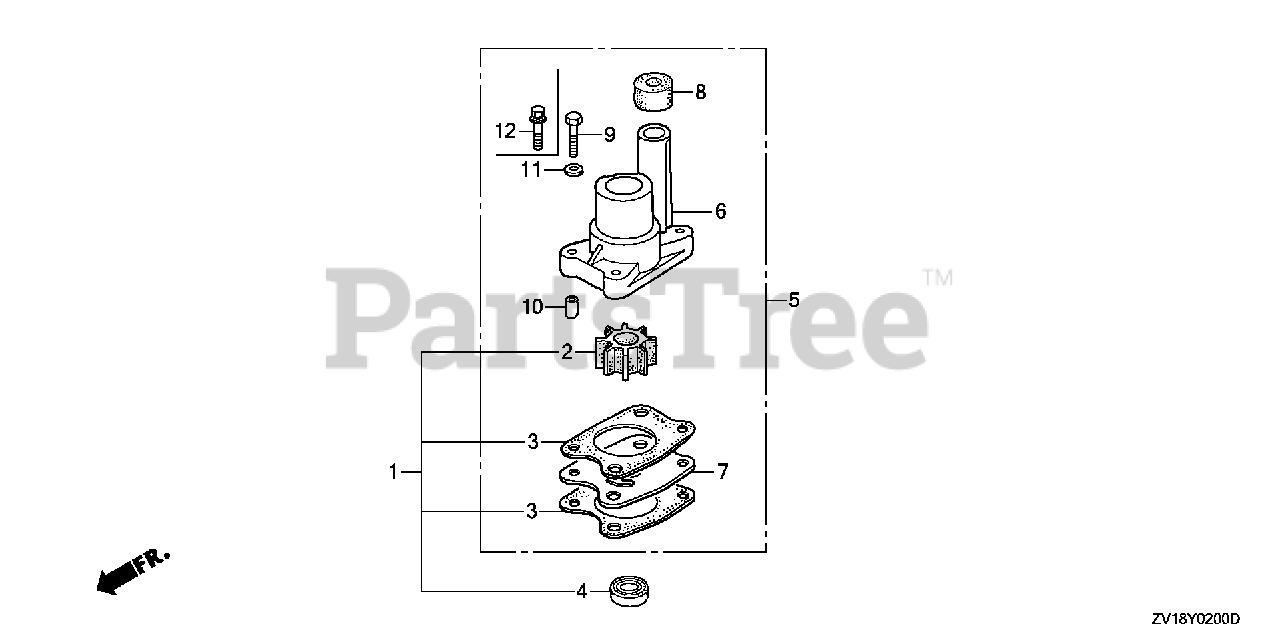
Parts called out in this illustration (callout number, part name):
1	IMPELLER KIT, WATER PUMP
2	IMPELLER, PUMP
3	GASKET, IMPELLER
4	SEAL, WATER (13MM) (ARAI)
5	PUMP KIT, IMPELLER
6	HOUSING, IMPELLER
7	COVER, IMPELLER
8	RING, WATER TUBE SEAL
9	BOLT, HEX. (6X28)
10	COLLAR B, DISTANCE
11	WASHER, PLAIN (6MM) Use from Frame SN 4800713.
12	BOLT-WASHER (6X29)
